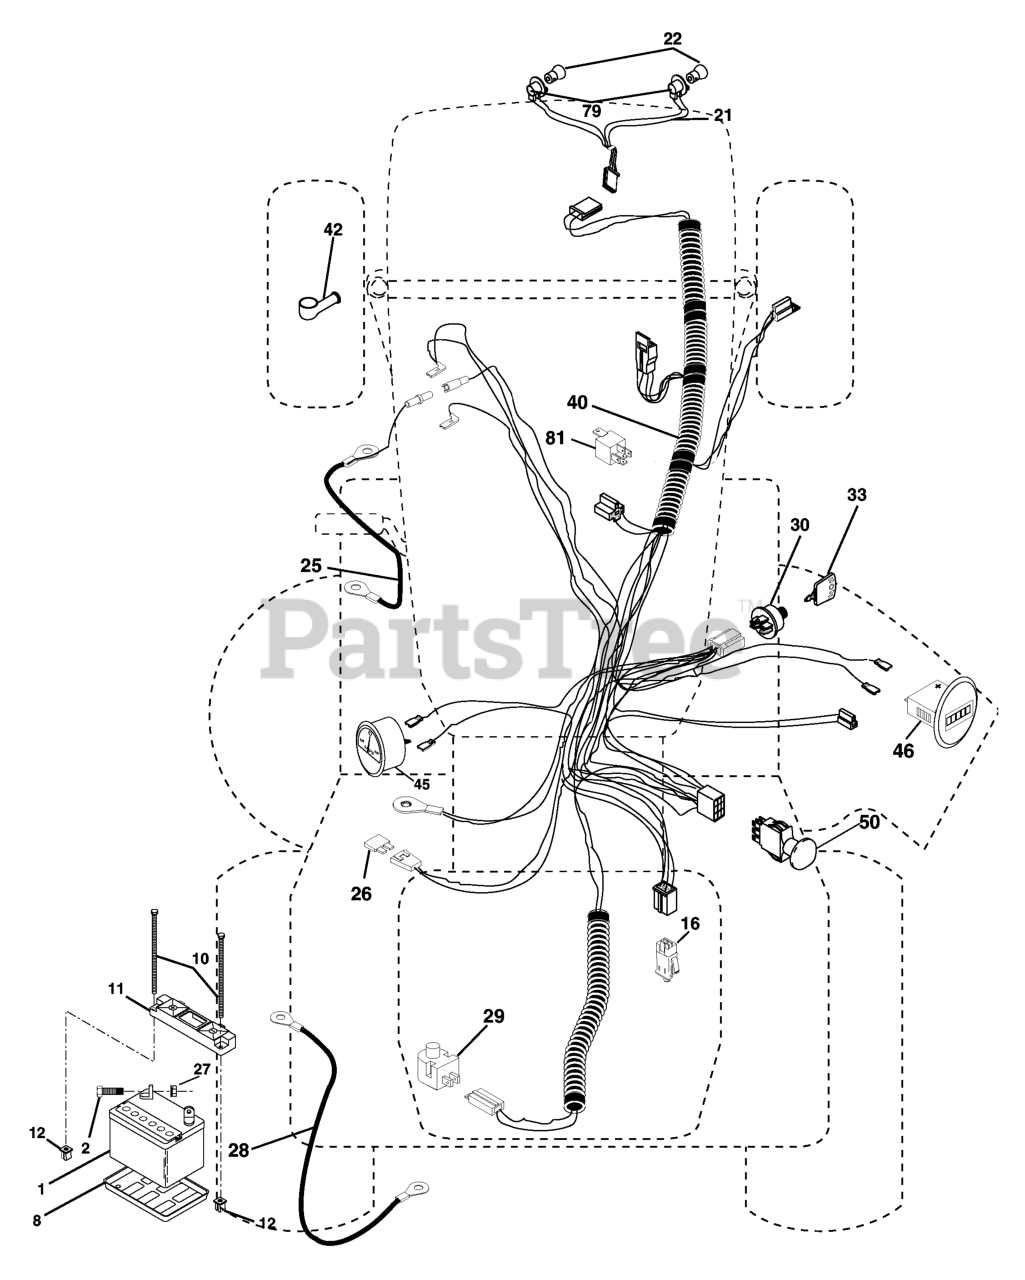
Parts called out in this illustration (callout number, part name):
1	BATTERY 12V .35 AMP
2	BOLT.HEX.1/4.X.3/4.DICHROMATE
8	BATTERY TRAY T
10	BOLT 1/4-20 X 7.5
11	BATTERY HOLDDOWN FRONT MOUNT
12	NUT, PUSH NYLON 1/4" BATTERY
16	SWITCH INTERLOOK PUSH-IN
21	HARNESS.W/LIGHT SOCKET
25	CABLE.4GA.RED.W/16GA.RED.WIRE
27	NUT
28	CABLE, GROUND
29	RP.SWITCH.PLUNGER.NC.GRAY
30	IGNITION SWITCH
33	KEY MLD GEN DELTA
40	HARNESS.IGNITION.VGT.NO.RELAY
42	COVER.TERMINAL.RED
45	RP AMMETER.ROUND.SILVER.DELTA
46	RP HOURMETER SNAP-IN
50	RP.PTO.SWITCH.8 TERMINAL.BLACK
79	BULB HOLDER ASM.
81	RELAY.ASSY.T
